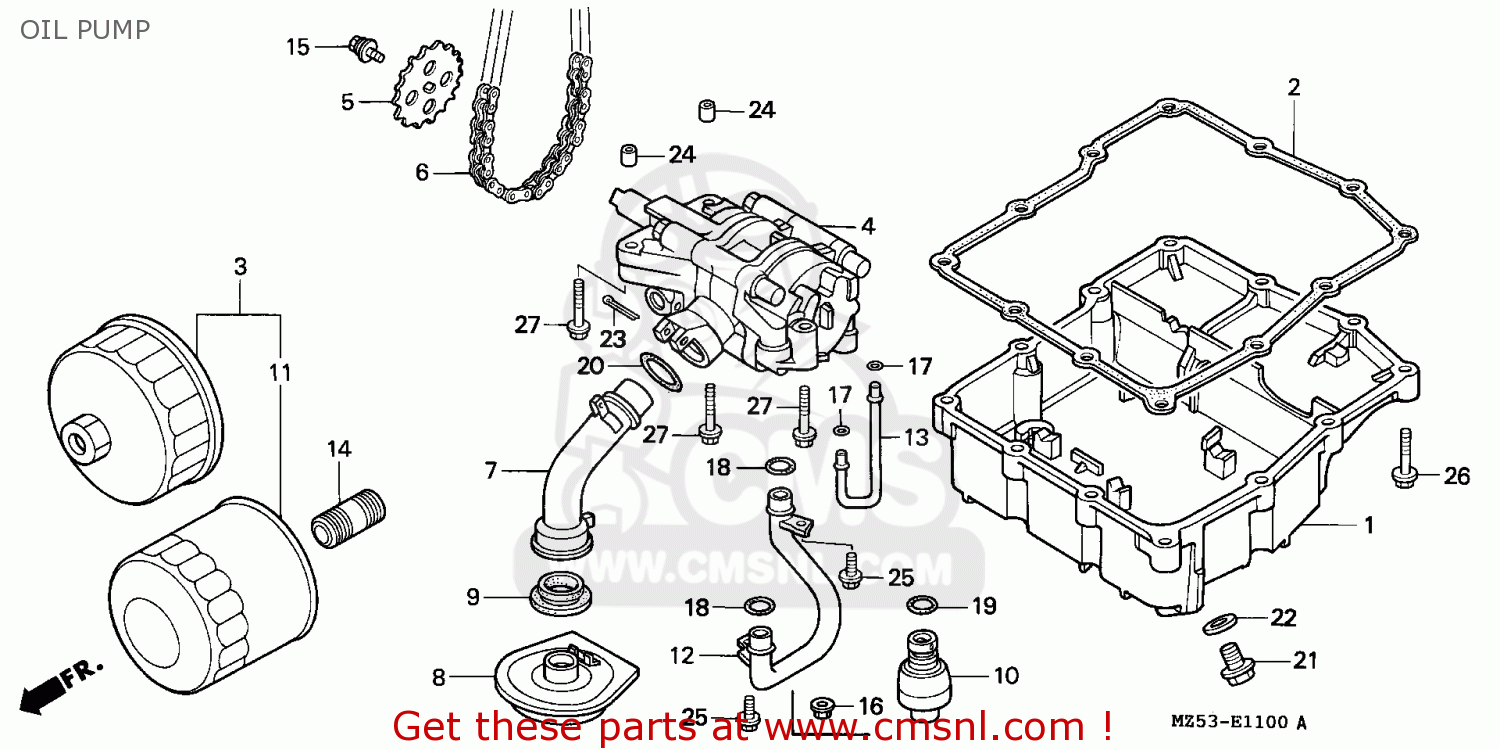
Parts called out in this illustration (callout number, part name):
1	OIL PAN
2	GASKET,OIL PAN (NAS)
3	FILTER SET,OIL
4	PUMP ASSY,OIL
5	SPROCKET,OIL PUMP
6	CHAIN,OIL PUMP
7	PIPE OIL STRAINER
8	STRAINER COMP,OIL
9	PACKING,OIL STRAI (NAS)
10	VALVE ASSY,RELIEF
11	CARTRIDGE,OIL FIL
12	PIPE COMP A,OIL
13	PIPE B,OIL
14	BOSS, OIL FILTER
15	BOLT-WASHER,6X12
16	NUT,U.,6MM
17	O RING,6X2
18	O-RING,14.7X3.7
19	O-RING,14.8X2.2
20	O-RING 21.2X2.4
21	BOLT DRAIN 12MM
23	PIN,SPLIT, 2.0
25	BOLT,FLANGE 6X14
26	BOLT,FLANGE,6X28
27	BOLT,FLANGE,6X40
